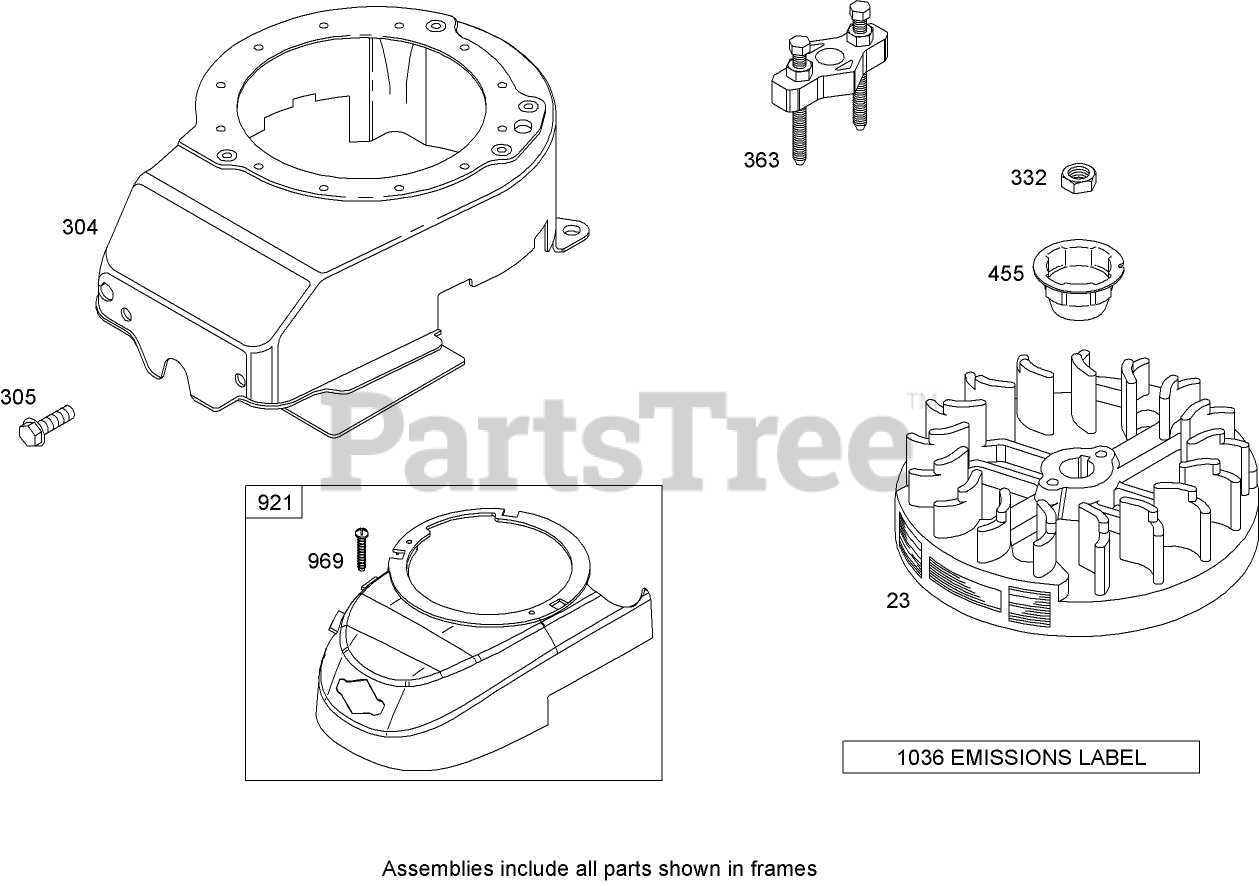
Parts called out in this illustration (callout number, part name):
23	Flywheel
304	Housing-Blower
305	Screw
332	Nut
363	Puller-Flywheel
455	Gasket-Passage, Breather
921	Cover-Housing, Blower
969	Screw
1036	Loose Parts Package
